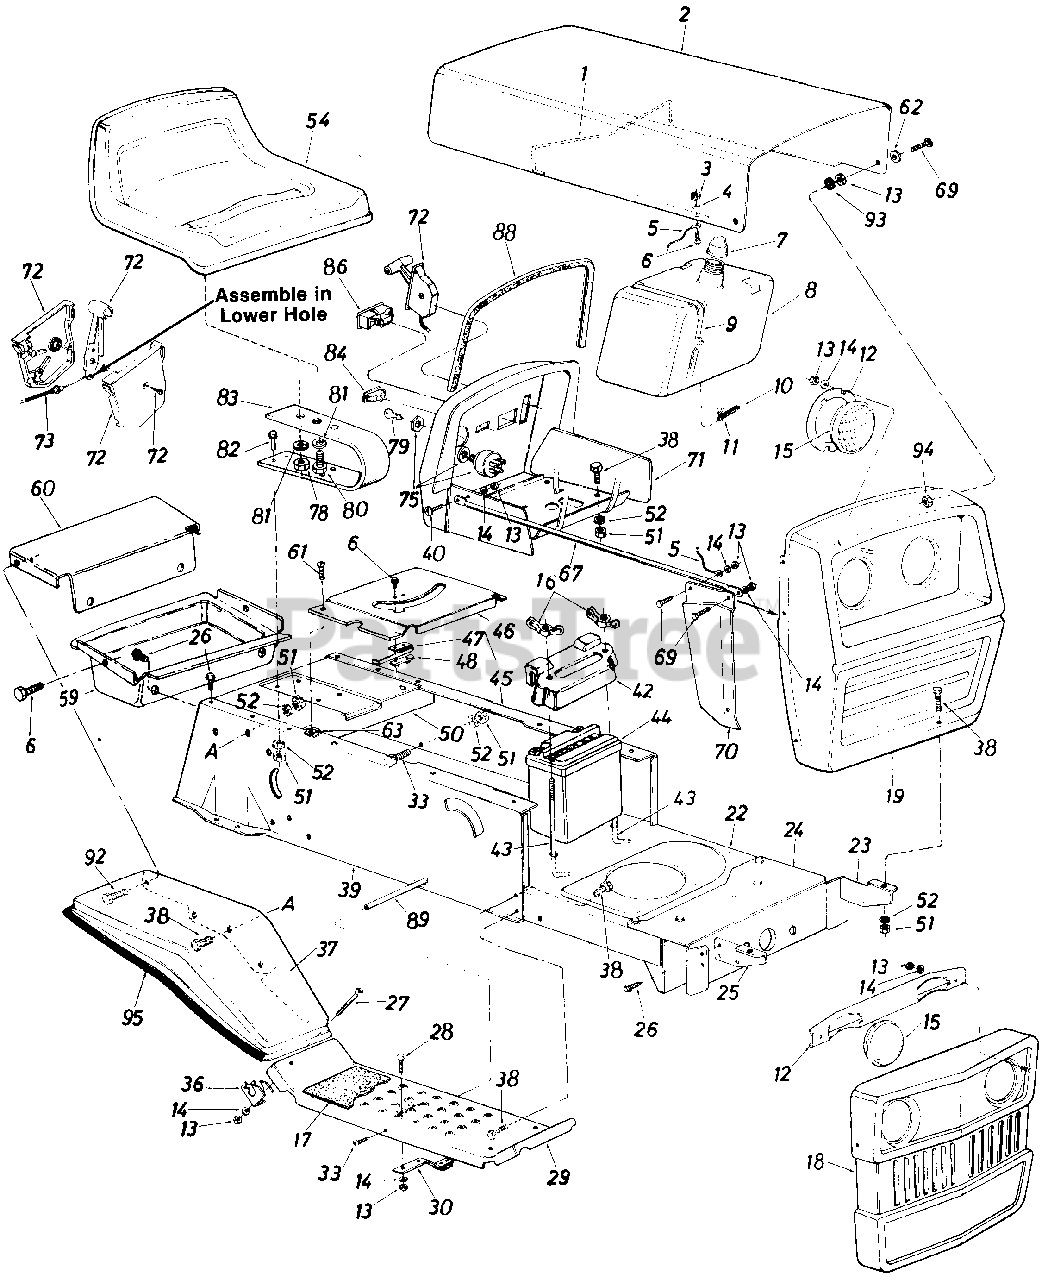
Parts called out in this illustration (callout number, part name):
1	Hood Spring
2	Hood
3	Hex Sems Nut #10-24 Thd.
4	Fl-Wash. .281" I.D. x .62" O.D. x .051
5	Hood Stop 7" Lg.
6	Truss Hd. Scr. #10-24 x 1/2"
7	Fuel Cap Gauge
8	Fuel Tank
9	Tie Strap
10	Fuel Line
11	Hose Clamp
12	Headlight Retainer
13	Hex Nut 1/4-20 Thd.
14	L-Wash. 1/4" I.D.
15	Headlight
16	Wing Nut 1/4-20 Thd.
17	Foot Pad
18	Grille Ass'y.
22	Lower Frame
23	Grille Mount Brkt.-L.H.
24	Front Pivot Brkt.
25	Grille Mount Brkt.-R.H.
26	Hex Wash. Hd. AB-Tap Scr. 5/16 x .75" Lg.
27	Truss Hd. Scr. 1/4-20 x 1.75" Lg.
28	Carriage Bolt 1/4-20 x .62" Lg.
29	Running Board
30	Blade Brake Ass'y.
33	Truss Mach. Scr. 5/16-18 x .75" Lg.
36	Fender Clamp
39	R.H. Side Frame
40	Hex Bolt 1/4-20 x .62" Lg.
42	Battery Cover
43	Battery Hold Down Rod
44	12-V Battery
45	L.H. Side Frame
46	Transmission Panel
47	Reverse Safety Switch
48	Insulator Nut Plate
50	Hitch Plate
51	Hex Nut 5/16-18 Thd.
52	L-Wash. 5/16" I.D.*
54	Seat Ass'y.
59	Tool Tray
62	Fl-Wash. .296 I.D. x .62 O.D.
63	Speed Nut #10Z
67	Grille Support Rod
69	Truss Hd. Scr. 1/4-20 x .75" Lg.
70	R.H.-Grille Side Panel
71	Dash Panel Ass'y.
72	Throttle Control Box Ass'y.
73	Throttle Control Wire
75	Ignition Switch
78	Hex Nut 1/2-13 Thd.
79	Ignition Key
80	Hex Bolt 1/2-13 x 1.00" Lg.
81	L-Wash. 1/2" I.D.
82	Hex Bolt 5/16-18 x 1.00" Lg.
83	Seat Spring
84	Light Switch
86	Ammeter
88	Molding Strip 27" Lg.
89	Running Board Rod
92	Thread Rolling Scr. 1/4-20 x .50" Lg.
93	RubberWash. 1/2" I.D. x 1.0 O.D. x .25"
94	Hex Sems Ins. L-Nut 1/4-20 Thd.
95	Trim Strip
